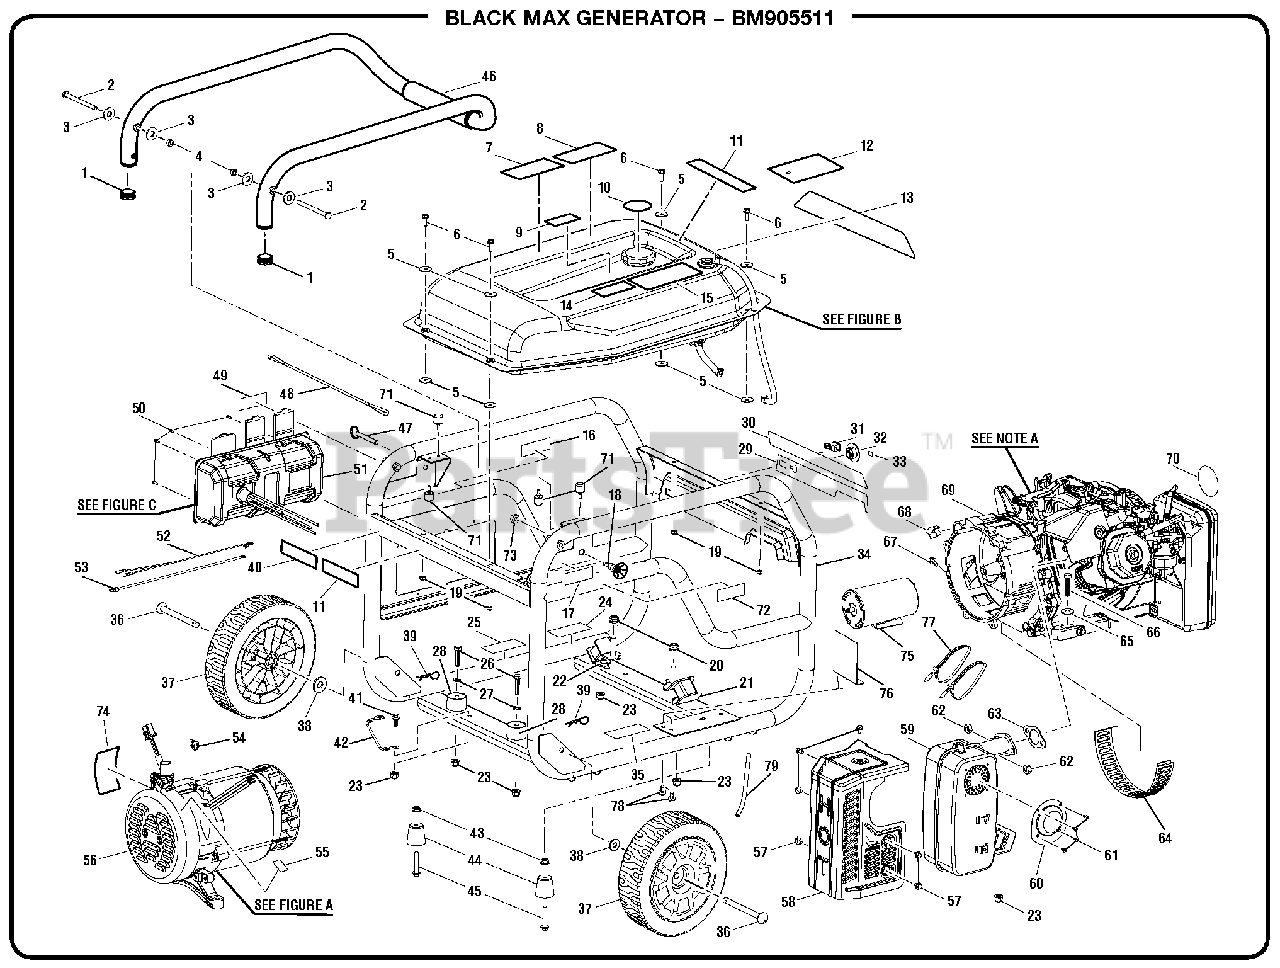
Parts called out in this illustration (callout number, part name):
1	End Cap (31 mm)
2	Pivot Pin, Handle 5/16-18 x 3.875 in.)
3	Washer (5/16 in.)
4	Hex Nut (M8)
5	Washer (1/4 in.)
6	Bolt (M6 x 25 mm, Flange Hex Hd.)
7	Fire Danger Label
8	CPSC Label
9	E85 Label
10	Fuel Stabilizer Label
11	Fire Distance Label (Eng/Sp)
12	Warning Hangtag
13	Logo Label (Black Max, Long)
14	Fuel Stabilizer Label (Spanish)
15	Danger Label
16	Logo Label (Black Max, Small)
17	Handle Release Label
18	Handle Release Pin
19	Lock Nut (M6)
20	Lock Nut (M10)
21	Engine Isolator (Large)
22	Engine Isolator
23	Flange Lock Nut (M8)
24	Inquires label
25	Lubricant Label
26	Bolt (M8 x 35 mm, Hex Hd.)
27	Lock Washer (ID8.5 x OD14.8 x 2t)
29	Start Label
30	Performance Label
31	On/Off Switch
32	Fuel Valve Bezel
33	Fuel Label
34	Frame Assembly
35	Combustion Label (Eng/Sp)
38	Washer (ID10 x OD19.75 x 2t)
39	Hitch Pin
40	Ground Warning Label
41	Bolt (M8 x 16 mm, Flange Hex Hd.)
42	Ground Wire Assembly
43	Lock Nut (M8)
44	Foot Assembly
45	Bolt (M8 x 45 mm, Flange Hex Hd.)
46	Handle Assembly
47	Release Pin
49	Lock and Pin Label
50	Screw (6-20 x 3/8 in., Pan Hd.)
51	Control Panel Assembly (See Fig. C)
52	Wire Assembly (Black)
53	Wire Assembly (Green)
54	Ground Lug
55	Ground Label
56	Generator Head Assembly (See Fig. A)
57	Bolt (M6 x 9 mm, Flange Hex Hd.)
58	Heat Shield
60	Spark Arrestor
61	Screw (8-32 x 3/8 in., Pan Hd.)
62	Hex Nut (M8)
63	Exhaust Gasket
64	Fan Cover (Generator Head)
65	Washer (ID9 x OD25.4 x 2t)
66	Bolt (M8 x 16 mm, Flange Hex Hd.)
67	Bolt (M5 x 10 mm, Flange Hex Hd.)
68	Plug (Generator Head)
70	Recoil Housing Label
71	Handle Bumper
72	Hot Surface Label
73	Lock Nut (1/2-20)
74	Data Label
75	Carbon Canister
76	Canister Bracket
77	Zip Tie, (5-1/2 in., Black)
78	Screw (10-16 x 3/4 in.)
79	Purge Hose (230 mm)
